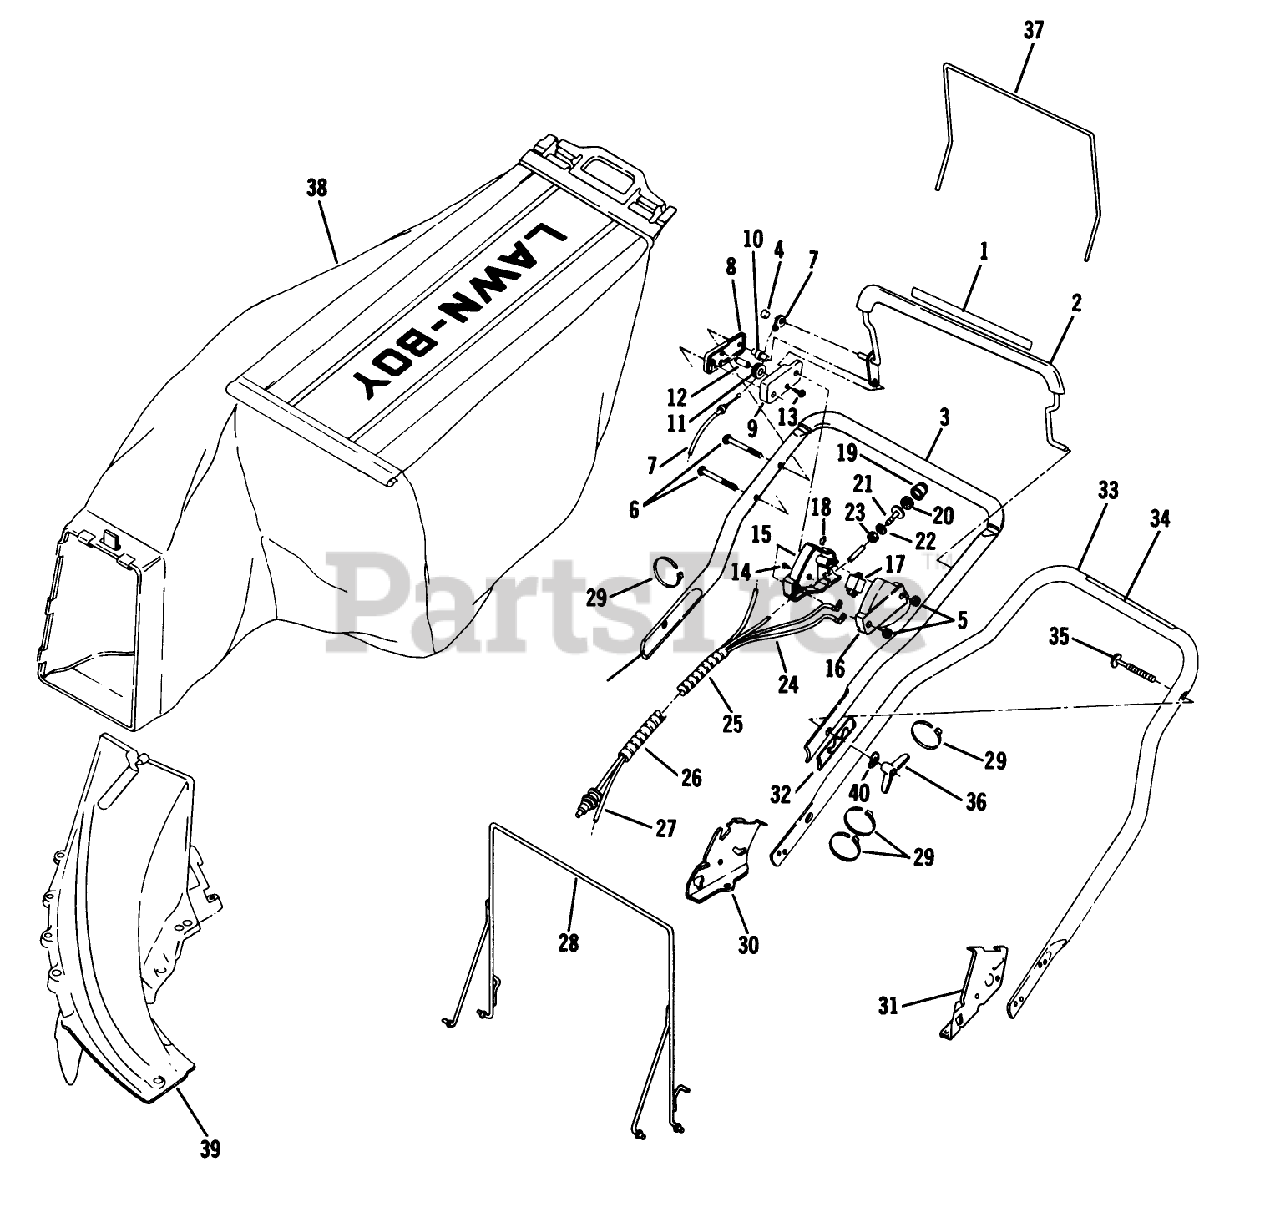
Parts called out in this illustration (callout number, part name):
5	NUT C/LOCK E
8	Control Case-Outer
10	COLUMN
12	PIN SKF
13	SCREW
20	FILTER S
23	LOCKNUT S
28	HANGER AY
32	BRACKET R/B 613462
35	Screw-Folding Handle
36	NUT-WING
37	HANGER
40	WASHER-CURVED
